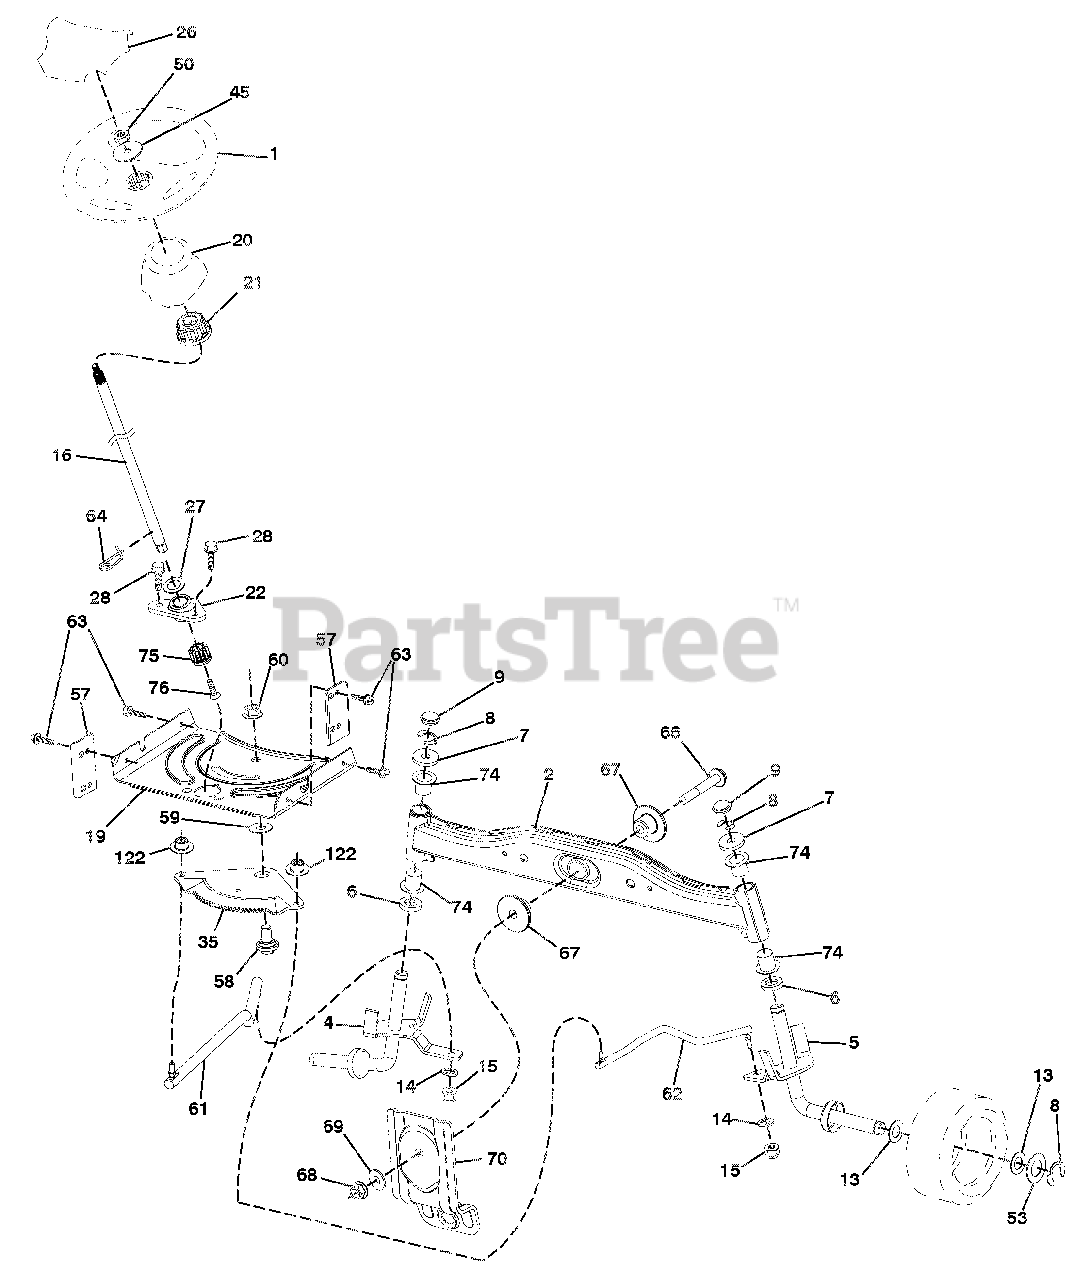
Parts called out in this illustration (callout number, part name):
1	WHEEL.STEERING.HARD RIM.BLACK
2	AXLE ASM.WELDED
4	SPINDLE.WELDED.LH.15"TEX
5	SPINDLE.WELDED.RH.15"TEX
6	WAHSER THRUST .75 X 1.230
7	WASHER.25/32 X 1-5/8 X 16GA.
8	RING.KLIP.#T5304-75
9	CAP.SPINDLE.FR.TOP.BLK.
13	WASHER.25/32 X 1 1/4 X 16 GA.
14	Washer, Lock 3/8
15	NUT.CROWNLOCK.3/8-24
16	SHAFT STEER
19	PLATE.STEER.DDL.NLT/NGT
20	BOOT.STEERING
21	ADAPTER.STEER
22	STEER.SUPT. LOWER
26	CAP WHEEL STEERING HRS/SRS BLK
27	WASHER 21/32 X 1 X 1 GA.
28	SCREW.HEXWSH THDR3/8-16X3/4.BL
35	GEAR SECTOR.PLATE.DDL.NLT/NGT
50	Nut, Hex, Flangelock 3/8-16
53	WASHER.HARDEN..793 X 1.637X060
57	BRACKET.UPSTOP.TEX
58	BOLT.SHOULDER.SECTOR.PIVOT.CFM
59	WASHER.THRUST.SECTOR.STEER.NLT
60	NUT.FLANGE LOCK.5/8-11
61	DRAGLINK.LH.BALLSTUD.DDL.
62	DRAGLINK.RH.BALLSTUD.DDL
63	SCREW.5/16-18X3/4.SMGML.TAP/BL
64	RETAINER.CLIP.SPRING.STEERING
66	BOLT.HEX.FGHD.7/16-14 X 3.SERR
67	BUSHING.PM.FRONT AXLE
68	NUT.LOCK.FLANGE.7/16-14.GR5
69	WASHER.1.5 X .505 X .118
70	BRACKET.DECK.SUSPENSION.FRONT
74	BEARING COL STRNG BLK
75	PINION
122	CAP GEAR SECTOR
